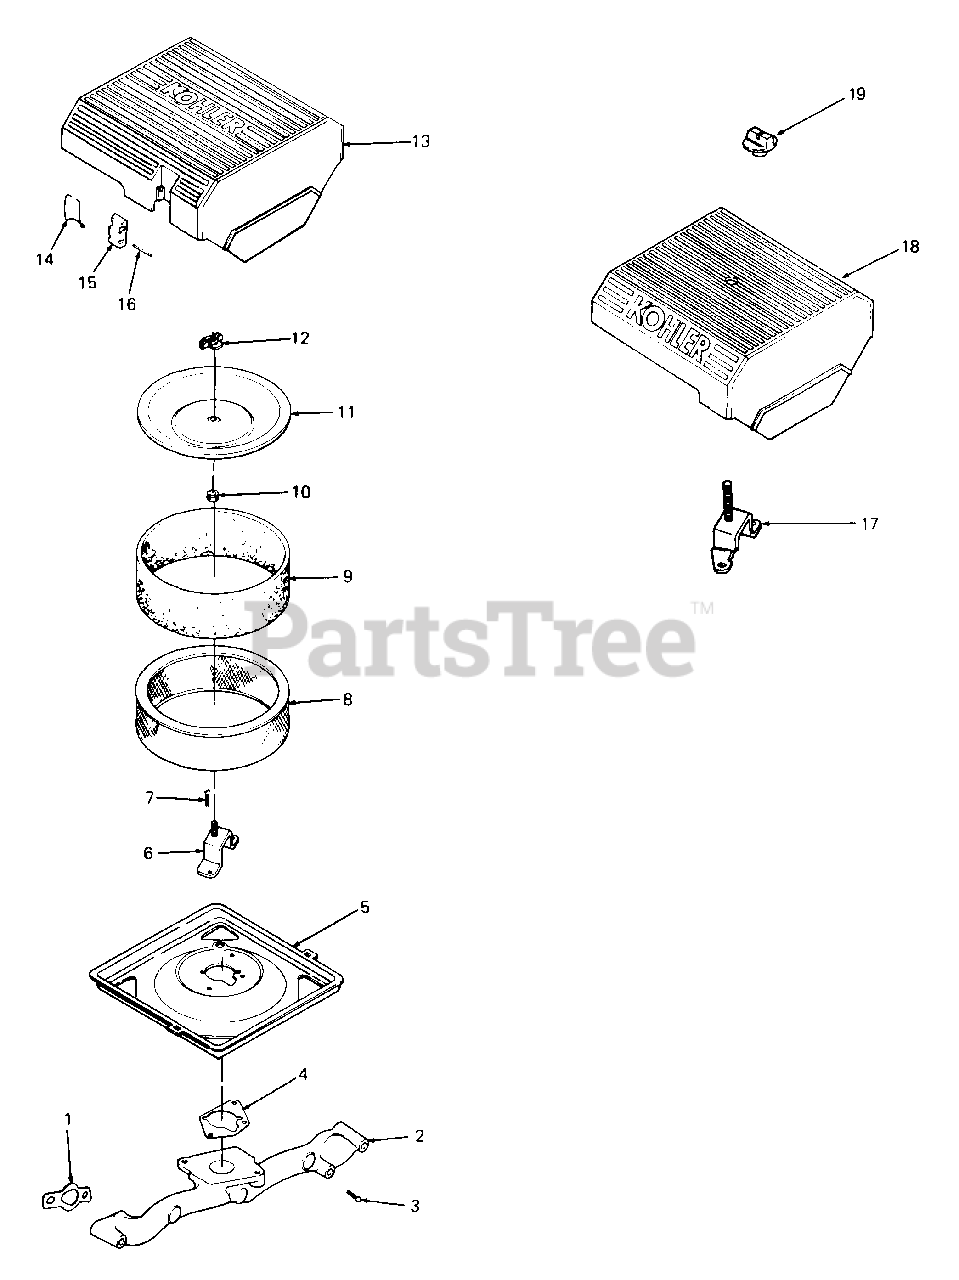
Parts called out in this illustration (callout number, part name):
1	Gasket, Intake Manifold
2	Manifold, Intake
3	Screw, M6 x 1.0 x 18
4	Gasket, Air Cleaner Base
5	Base, Air Cleaner
6	Bracket, Air Cleaner
7	Screw, M6 x 1.0 x 10
8	Element, Air Cleaner
9	Element, Pre-Cleaner
10	Seal, Air Intake
11	Cover, Inner Air Cleaner
13	Cover, Air Cleaner
14	Spring, Latch
15	Latch, Lever
16	Pin, ACR Control
17	Bracket, Air Cleaner
18	Cover, Air Cleaner
19	Knob, Cover
